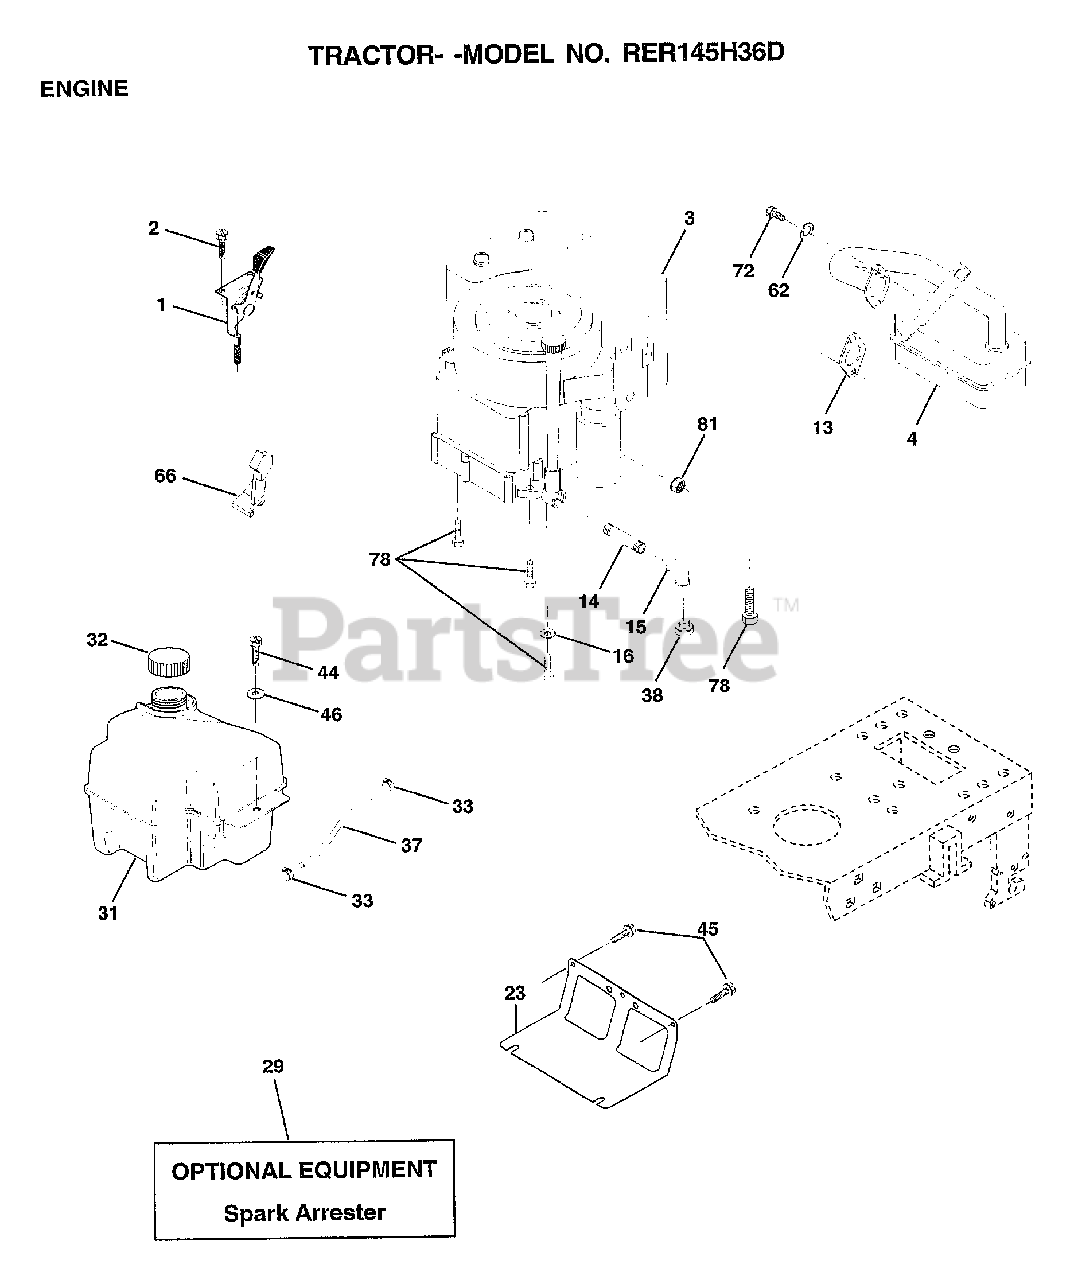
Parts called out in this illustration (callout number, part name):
1	CONTROL.THTL.23.5
2	SCREW LT
4	MUFFLER
14	PIPE NIPPLE
15	ELBOW
16	LOCKWASHER
23	SHIELD BROWNING
31	TANK.FUEL.FRONT.
32	CAP ASM FUEL
33	HOSE CLAMP
37	LINE FUEL
44	SCREW
45	SCREW
46	WASHER
62	LOCKWASHER
66	"STOP,DASH THROTT"
72	SCREW
78	SCREW
81	NUT
